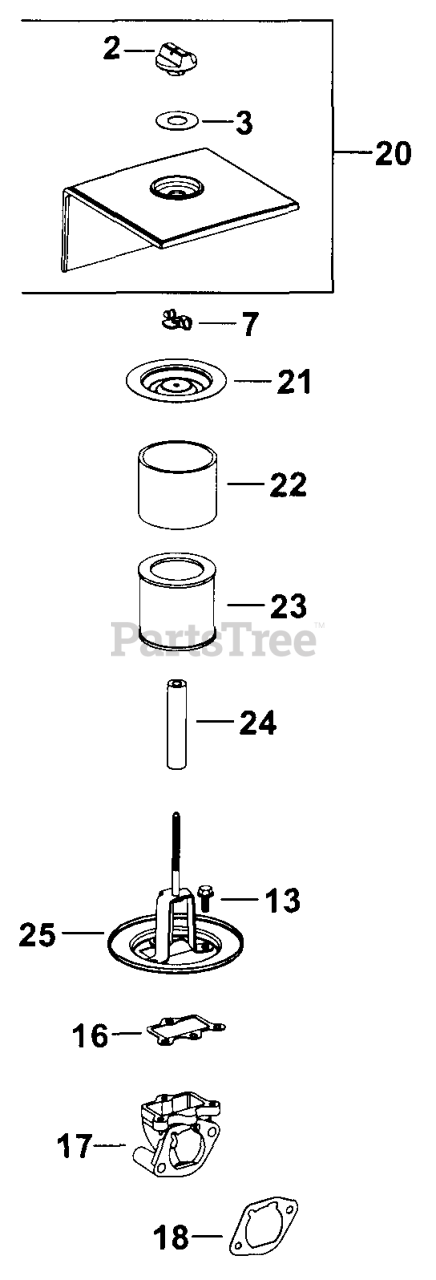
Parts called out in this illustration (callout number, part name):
2	KNOB, COVER
3	GASKET, AIR CLEANER COVER KNOB
7	NUT, WING
13	SCREW,FLG THD FRM M6X1.0X16-(#25086397S)
16	GASKET, AIR CLEANR BASE
17	ELBOW, AIR CLEANER
18	GASKET, AIR CLEANER BASE
20	KIT, AIR CLEANER COVER - DISCONTINUED
21	COVER, INNER AIR CLEANER - DISCONTINUED
22	PRE-CLEANER
23	ELEMENT, AIR FILTER
25	BASE, AIR CLEANER
